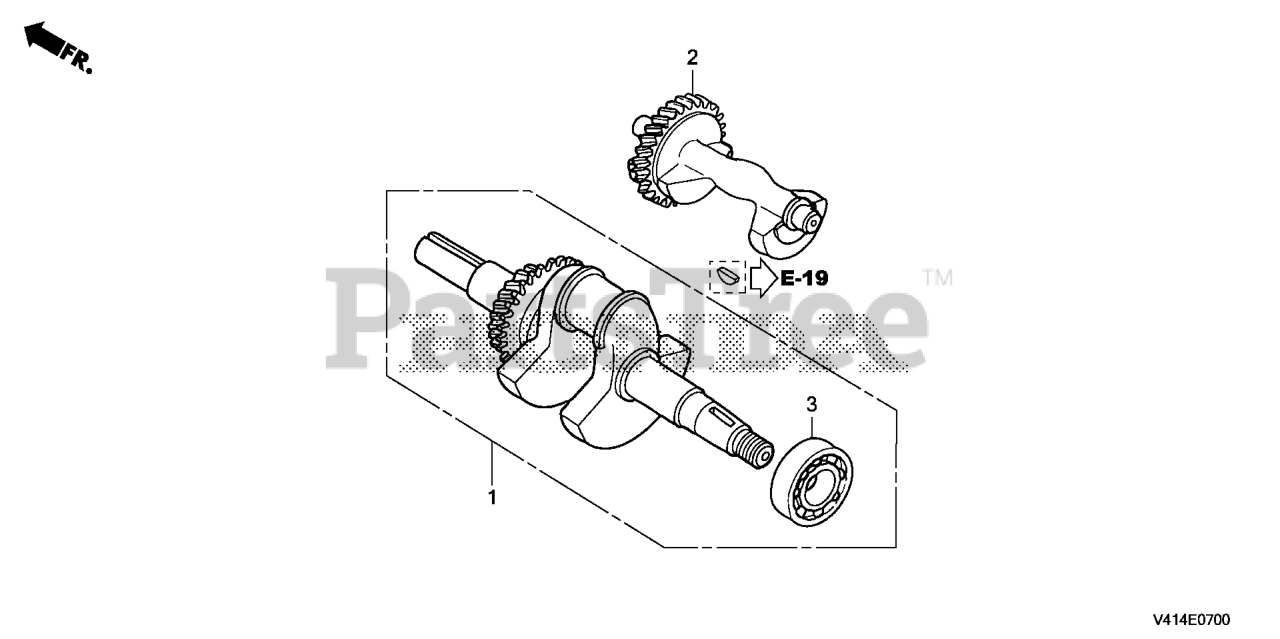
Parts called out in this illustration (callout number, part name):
1	CRANKSHAFT
2	WEIGHT, BALANCER
3	BEARING, RADIAL BALL (6207SH)
